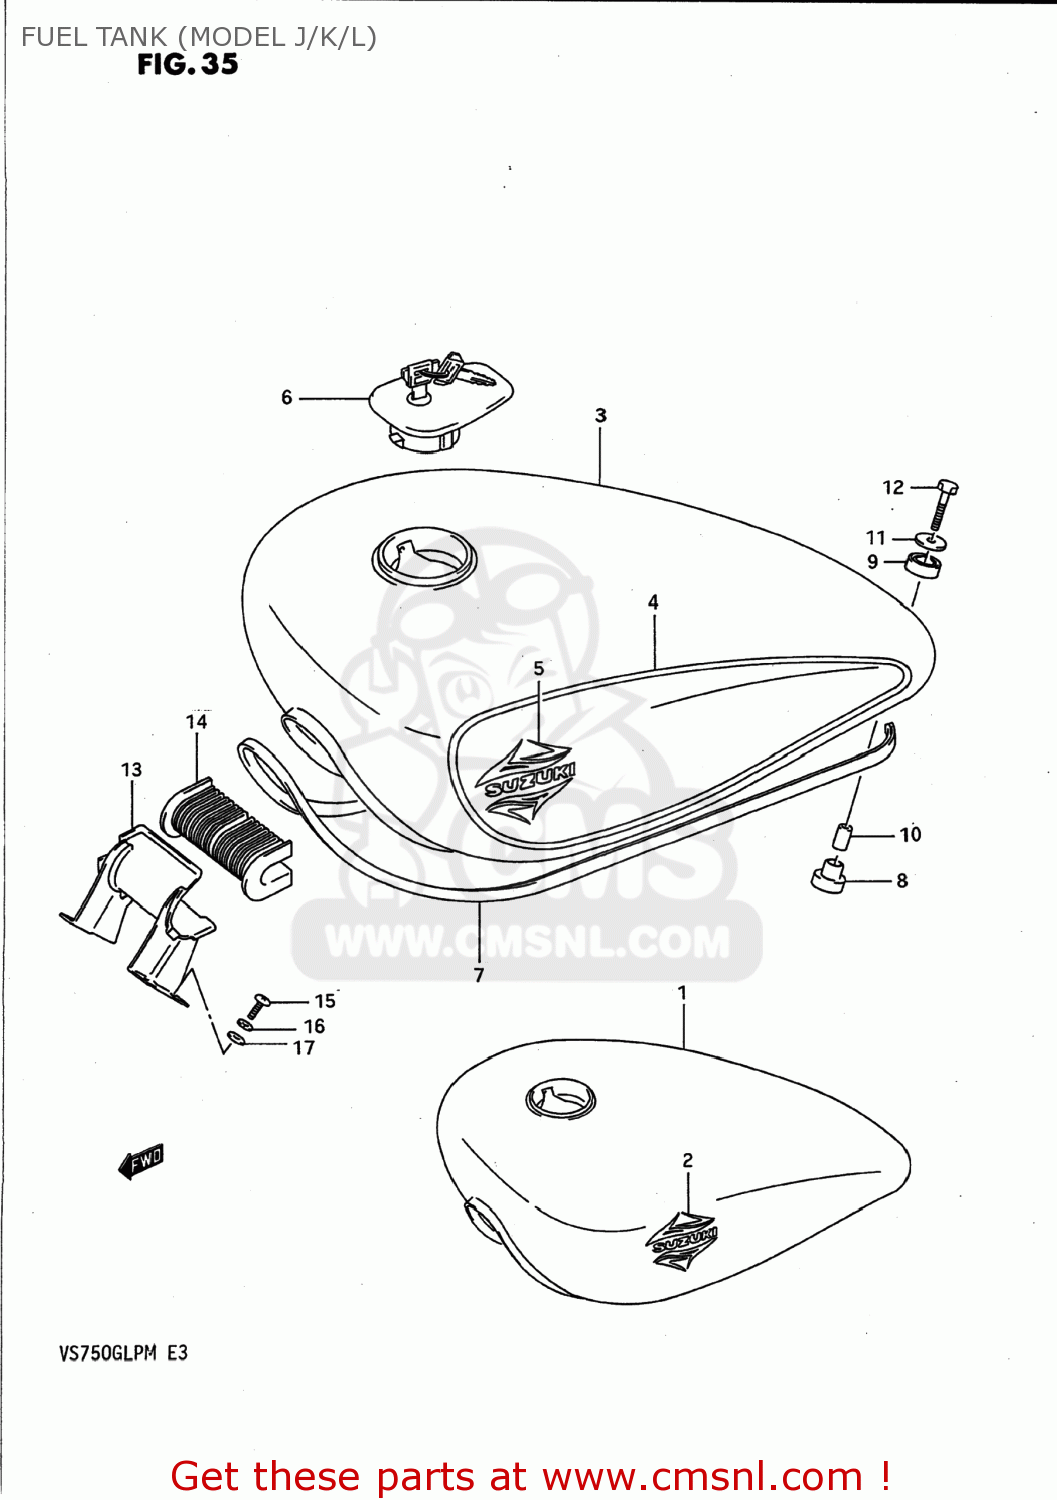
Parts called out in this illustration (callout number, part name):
1	TANK ASSEMBLY,FUEL
2	EMBLEM,FUEL TANK
3	TANK ASSEMBLY,FUEL
4	TAPE SET,FUEL TANK
5	EMBLEM
6	CAP SET,FUEL TANK
7	MOLDING,FUEL TANK
8	CUSHION
9	CUSHION
10	SPACER (6.4X9X21.5)
11	WASHER (6.5X24X1.6)
12	SCREW
13	BRACKET COMP,FUEL TANK
14	CUSHION,FUEL TANK FR
15	SCREW
16	WASHER,LOCK
17	WASHER
